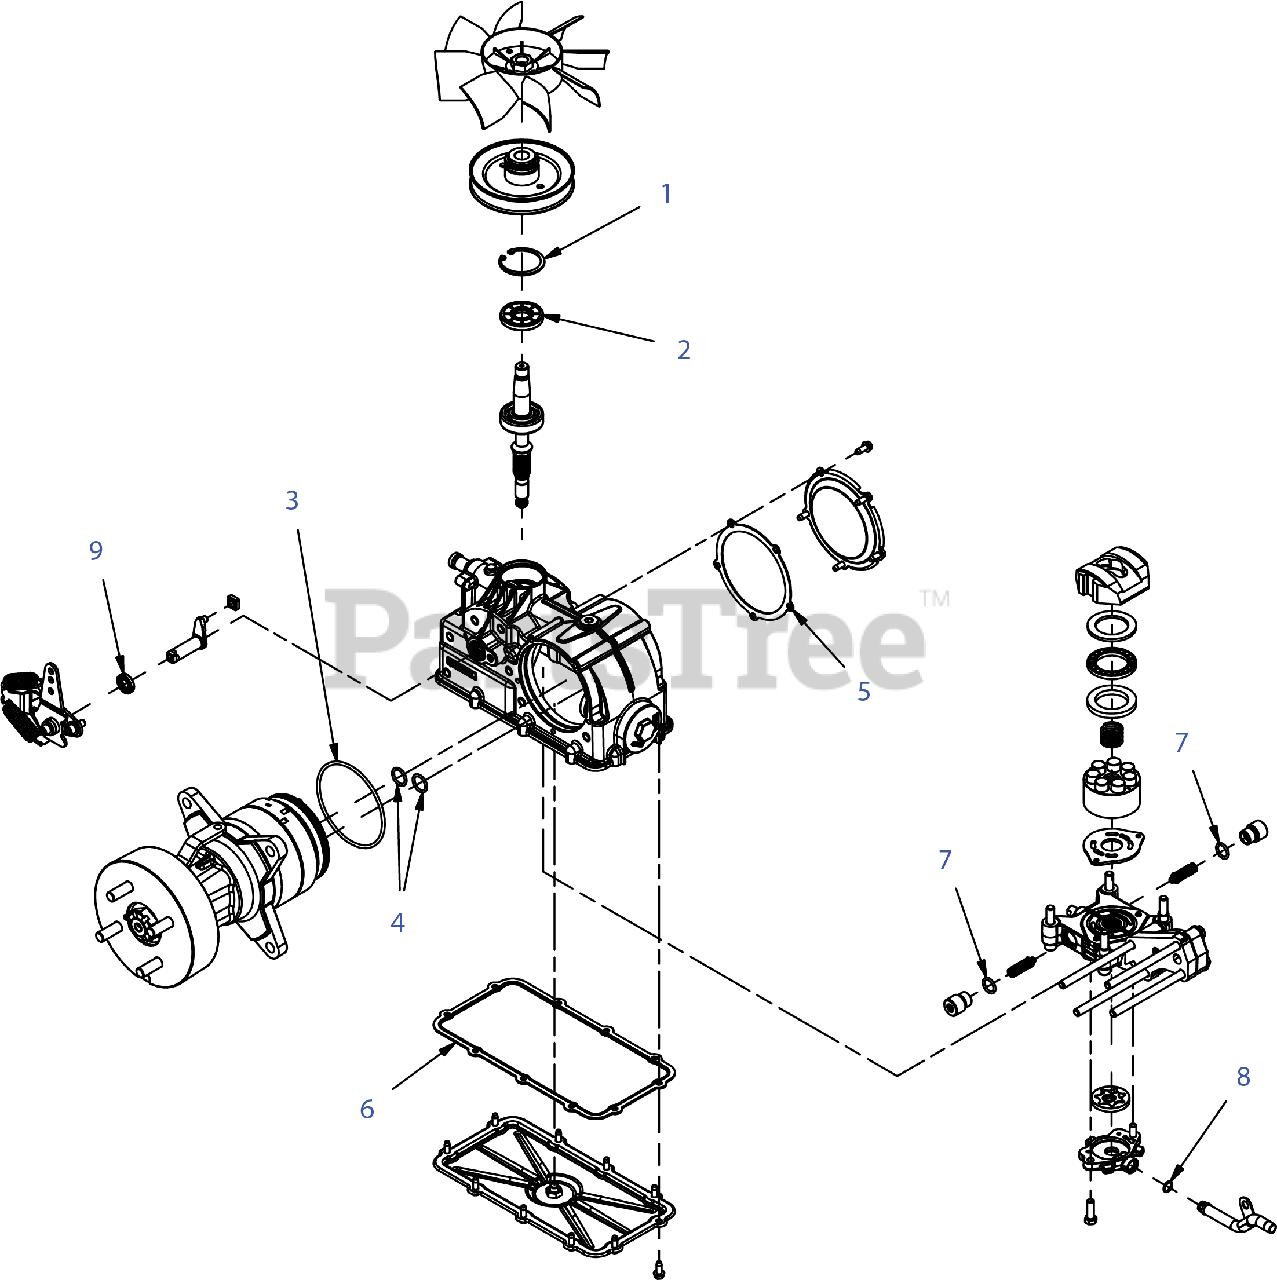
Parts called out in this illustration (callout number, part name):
1	RETAINING RING
3	PACKING PREFORMED O-RING SEAL
4	PACKING PREFORMED O-RING SEAL
5	SIDE COVER FE GASKET
6	BOTTOM COVER GASKET
7	PACKING PREFORMED O-RING SEAL
8	PACKING PREFORMED O-RING SEAL
9	SEAL TRUNNION ARM
